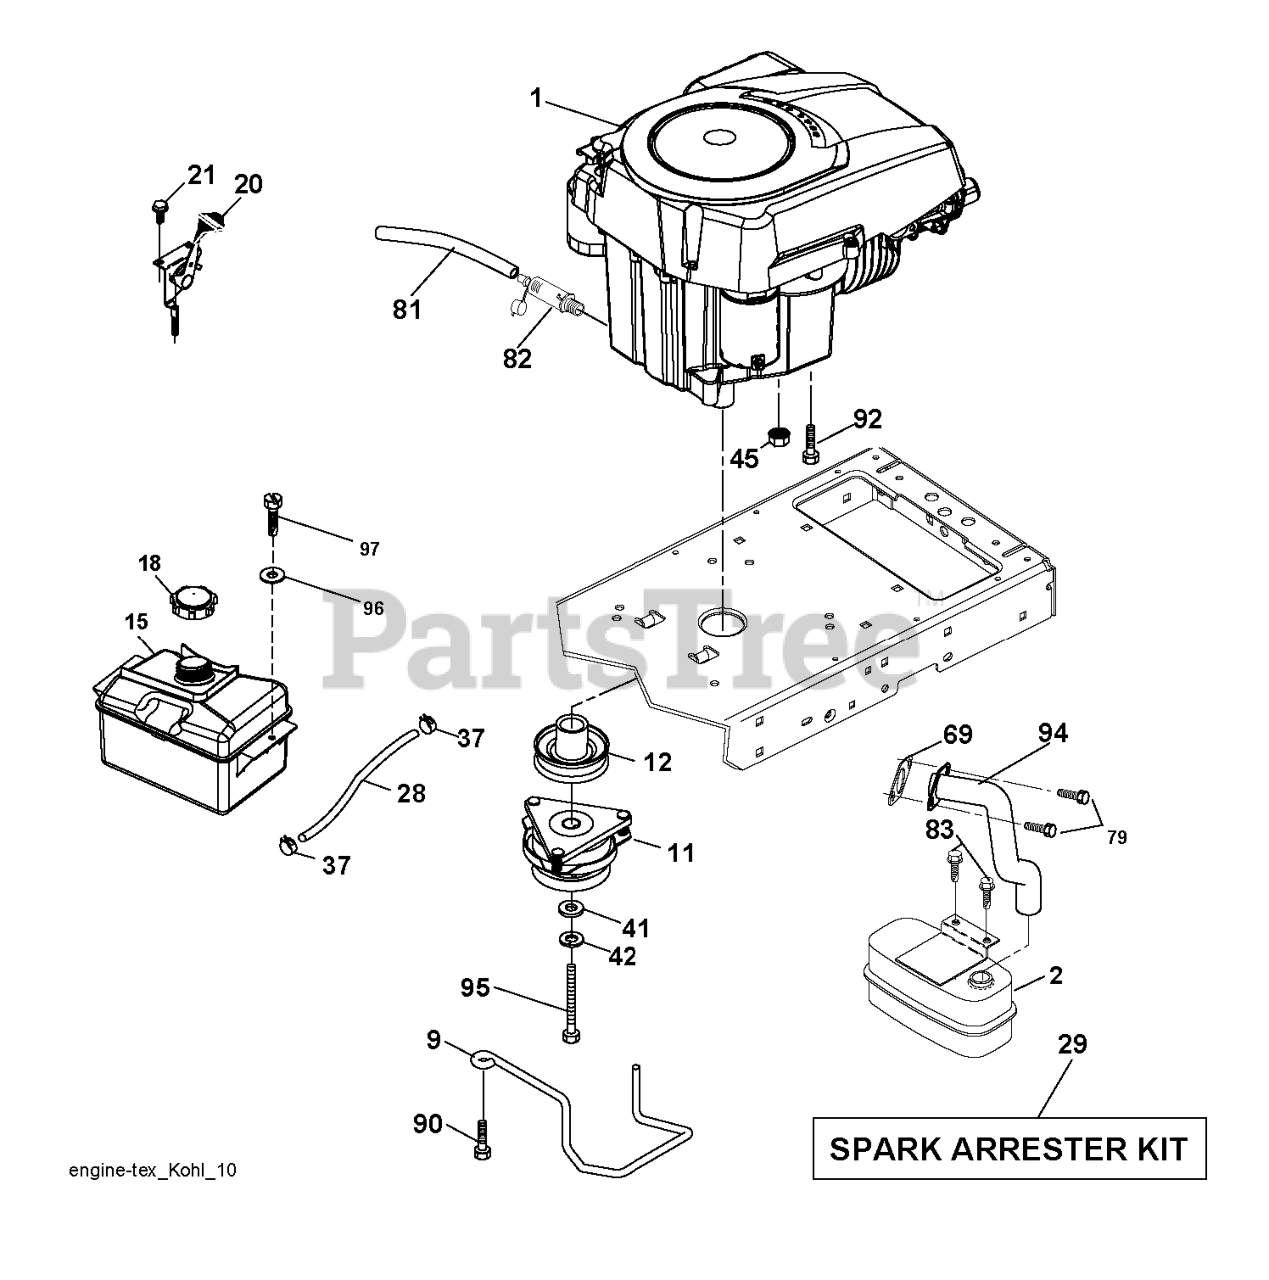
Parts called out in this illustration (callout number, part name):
2	MUFFLER.SINGLE.CYL.KOHL/B&S
9	KEEPER.BELT.ENGINE.4.2
11	RB.CLUTCH.OGURA.4.4.PD
12	PULLEY.ENGINE.TUFFTORQ
15	RP TANK FUEL FRT 1.5 GAL
18	FUEL CAP
20	CONTROL.TH/CK.C.
21	SCREW.#10 X 0.750.BOS
28	LINE.FUEL.20
29	KIT.SPARK ARRESTOR 794945 B&S
37	HOSE CLAMP
42	LOCKWASHER
45	NUT
69	GASKET.EXHAUST.KOHLER
79	SCREW.SOCKET HD.5/16-1
81	TUBE, DRAIN OIL ASM.
82	PLUG DRAIN OIL EASY
83	BOLT.5/16-18UNCX3/4 W/SEMS.BLK
90	SCREW 3/8-16X1
92	SCREW 3/8-16X1
94	RP.TUBE.EXHAUST.KOHL.COURAGE
95	BOLT HEX 7/16-20X4-1/4"
97	SCREW HEXWSHR 1/4-20X3/4
